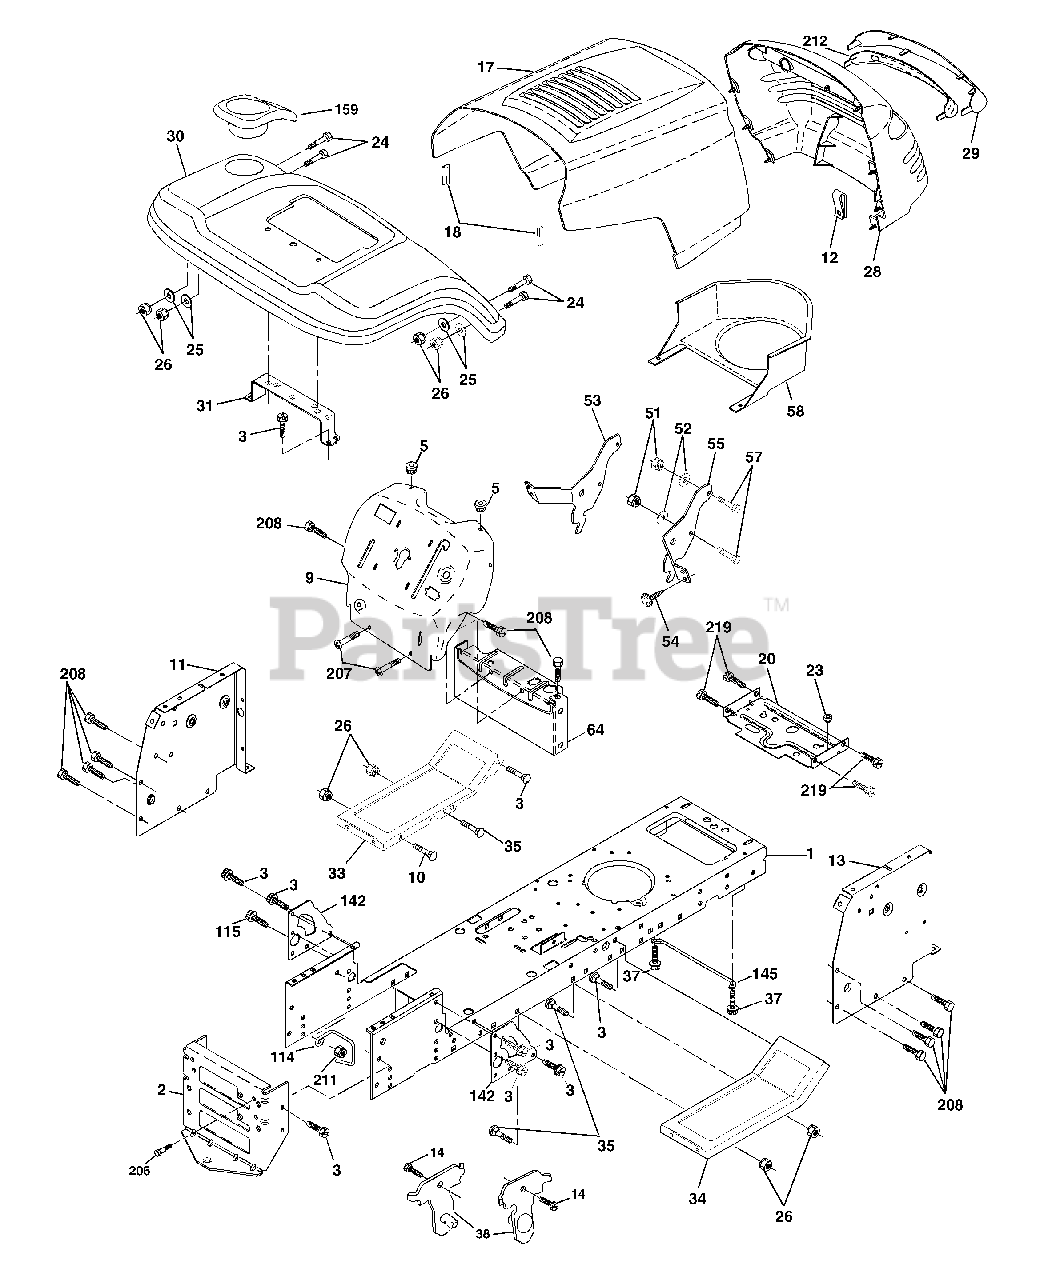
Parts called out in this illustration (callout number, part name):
1	Chassis
2	Drawbar
3	Screw 3/8-16x.75
5	Bumper Hood/Dash
9	Dash P/L
10	Bolt Carriage 3/8-16 x 1
11	Panel Dash Lh
12	Clip Tinnerman
13	Panel Dash Rh
14	Screw Thdrol 3/8-16 x 1-1/4
17	Hood LT/PL
18	Bumper Hood
20	Plate Mtg Battery Fuel Tank Fr
23	Bushing
24	Bolt Fin Hex 3/8-16 x 1 Gr 5
25	Washer 13/32 X 13/16 X 12 Ga
26	Nut Lock Hex W/Ins 3/8-16 Unc
28	Grille LT/PL
29	Lens LT/PL
30	Fender Footrest STLT Pnt
31	Bracket Support Fender
33	Footrest Pnt Lh
34	Footrest Pnt Rh
35	Bolt Rdhd Sht Sqnk 3/8-16 x 3/4
37	Screw Thdrol 6/16-18 x 1/2 TYT
38	Bracket Asm. Pivot Mower Rear
51	Nut Lock Hex W/Ins 1/4-20
52	Washer 9/32 x 7/8 x 16 Ga.
53	Bracjet Grukke Lh
54	Screw Hex Wshd 8-18 x 7/8
55	Bracket Grille Rh
57	Bolt Hex 1/4-20 x 3/4
58	Duct Air
64	Dash Lower STLT
114	Keeper Belt Rear Lh
115	Screw 3/8-16 x 1-1/4
142	Plate Reinforcement STLT
145	Rod Pivot Chassis/Hood
159	Cupholder
206	Bolt Shoulder 5/16-18
207	Screw Thdrol 5/16-18 x 1/2
208	Screw Thdrol 3/8-16 x 1/2
211	Nut Hex Flange Lock
212	Insert Lens Reflect P/L LT
219	Screw 5/16-18 x 3/4
